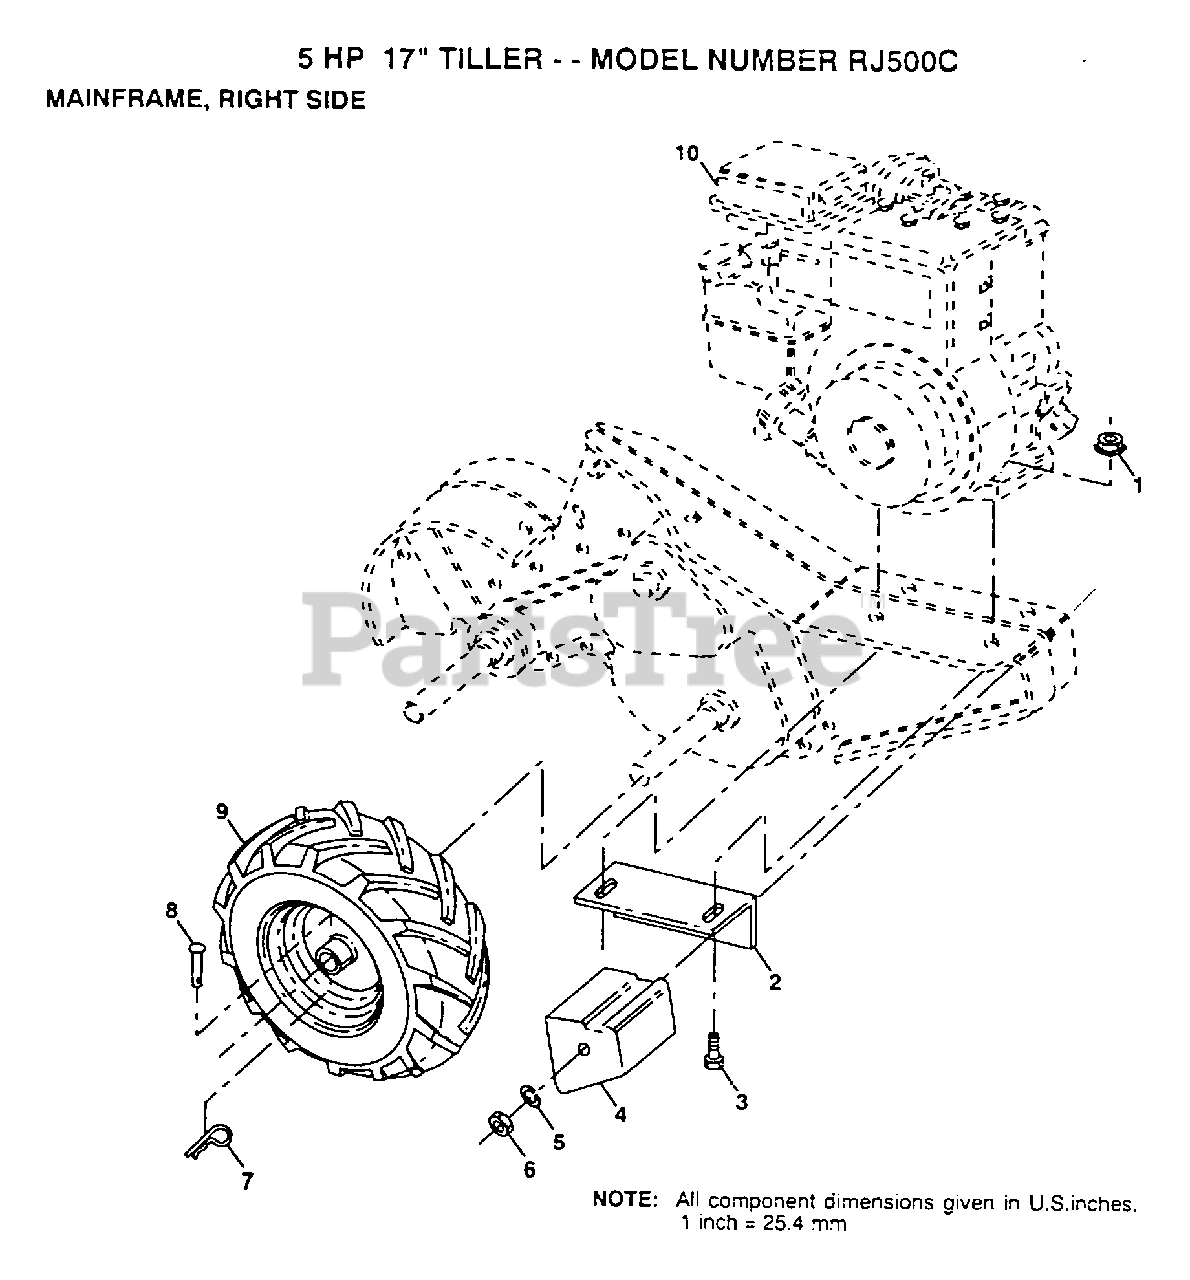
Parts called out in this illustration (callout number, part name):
2	BRACKET RH CRT
3	BOLT.HEX.5/16-1.5
4	COUNTERWEIGHT CRT
5	LOCKWASHER
6	NUT.HEX.3/8-16UNC
7	RETAINER M
8	RIVET.DRILL.1.75
9	TIRE.CHV.13X5.0-6
9	RIM
